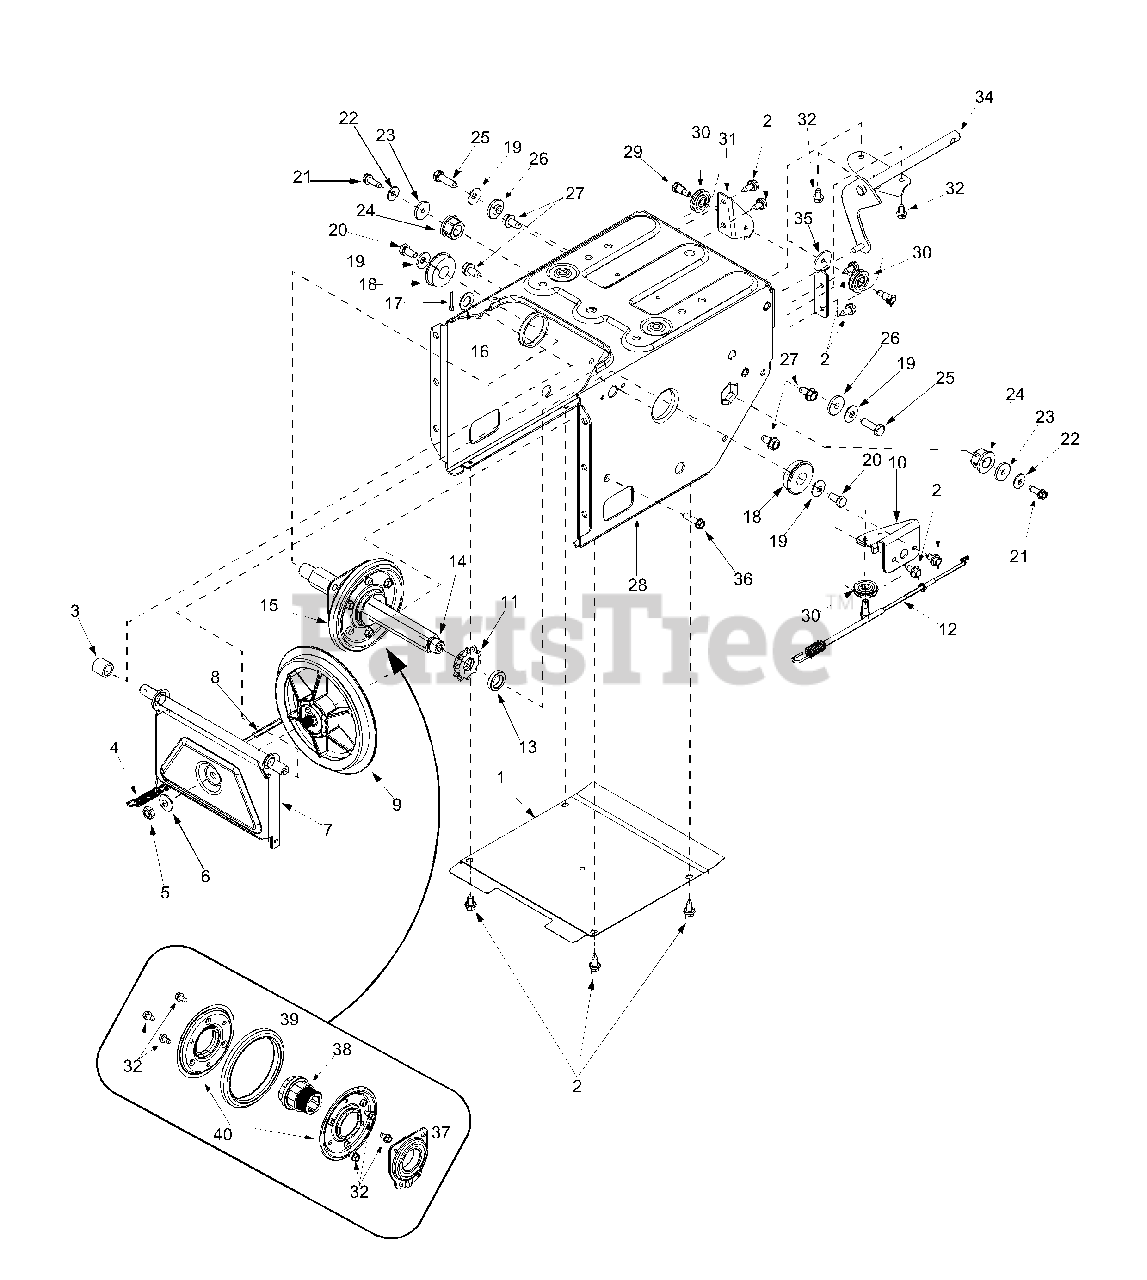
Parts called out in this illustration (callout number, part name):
3	Spacer .508 ID x .75 OD
4	Extension Spring
5	Jam Nut 3/8-24
6	Bell Washer .401 ID x .87 OD
9	Friction Disc
12	Auger Cable 44.75"
13	Spacer .675 ID x 1" OD
14	Hex Track Shaft
15	Friction Wheel Assembly
16	Flat Washer .536 ID x .93 OD
18	Ball Bearing
19	Bell Washer .34 ID x .872 OD
20	Hex Cap Screw 5/16-18 x .625
21	Tap Screw 1/4-20 x .75
22	Bell Washer .265 ID x .75 OD
23	Flat Washer 1/4 ID x .93 OD
24	Hex Flange Bearing
25	Hex Cap Screw 5/16-18 x 1"
26	Shoulder Spacer
27	Tap Screw 5/16-18 x .625
29	Hex Screw 1/4-28 x .375
30	Cable Roller
37	Friction Wheel Bearing
38	Friction Wheel Hub
39	Friction Wheel Rubber
40	Friction Plate
